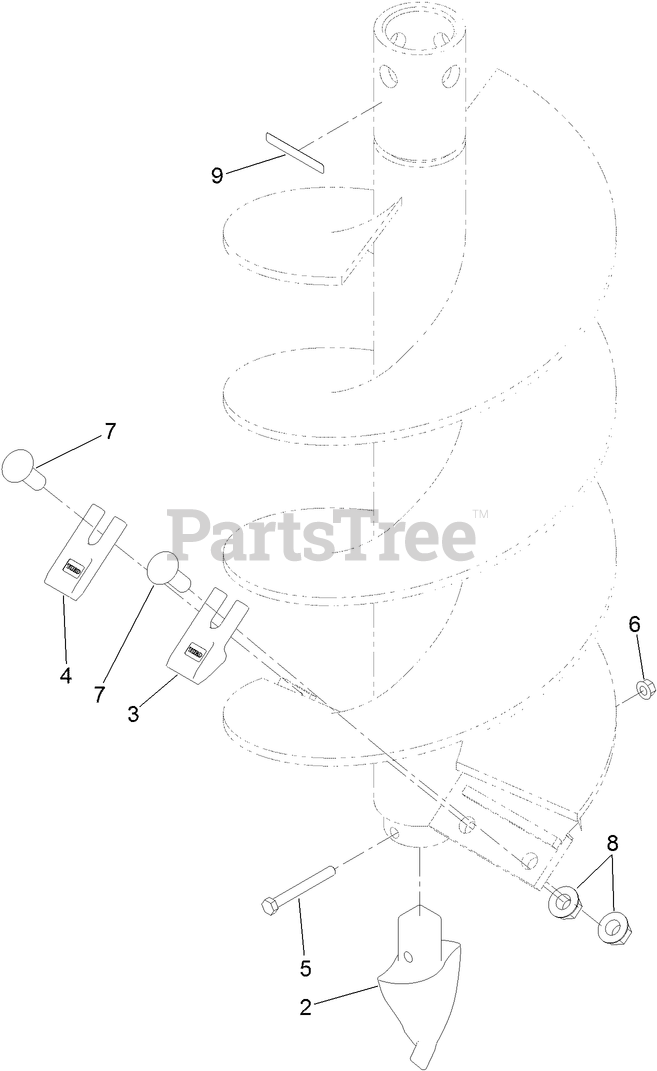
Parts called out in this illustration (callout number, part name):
2	PILOT-AUGER
3	TOOTH-OUTER
4	TOOTH-INNER
5	SCREW-HH
6	NUT-HF
7	SCREW-CARR
8	NUT-FLANGE
9	DECAL-WARNING
